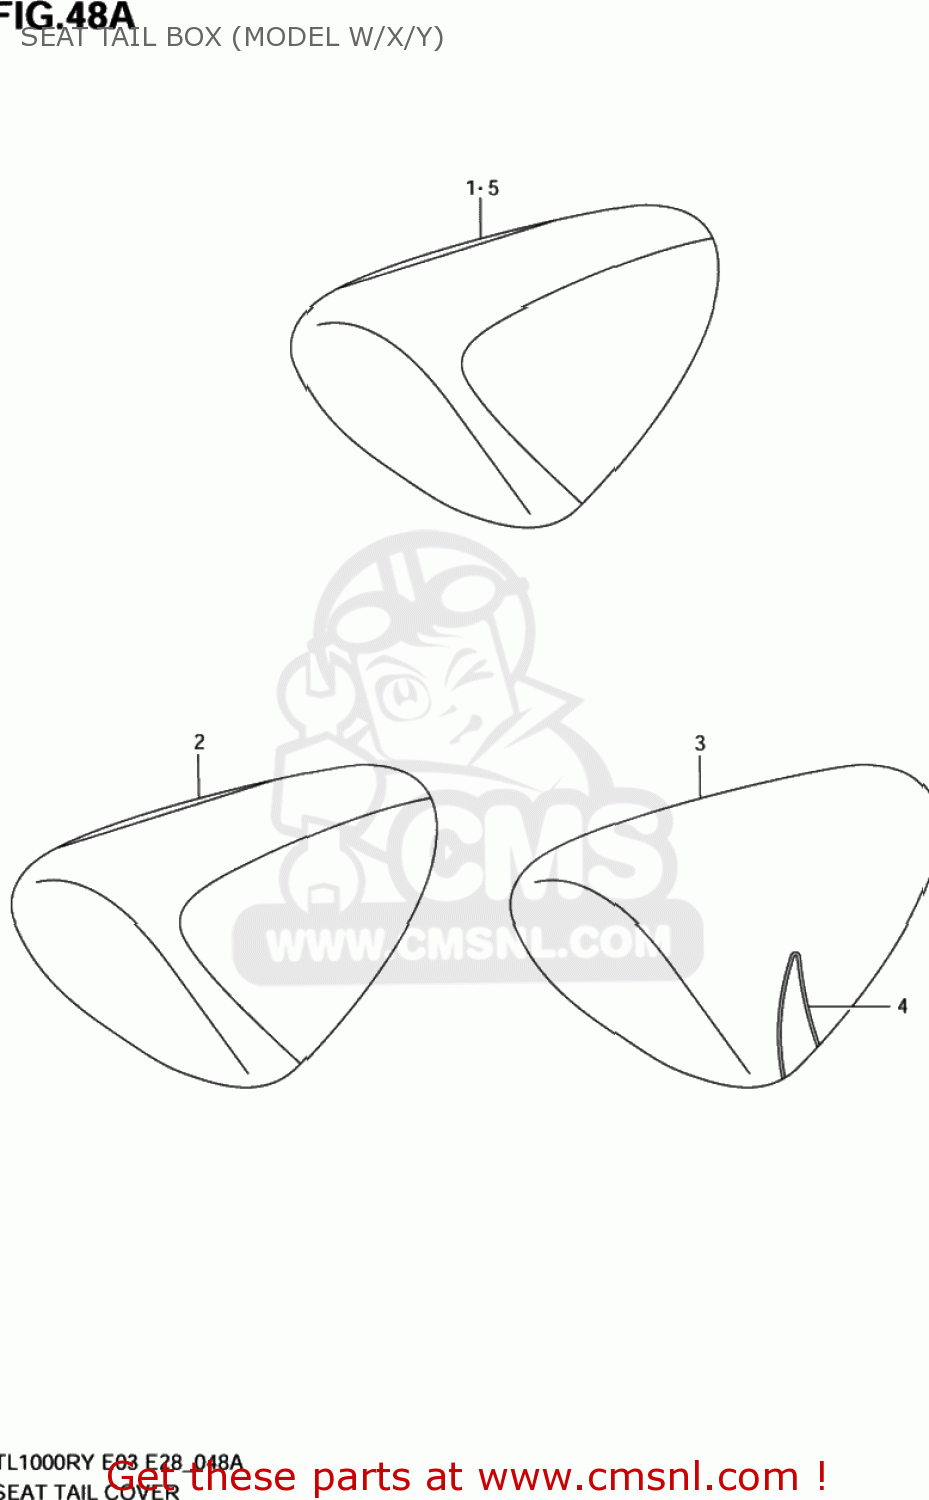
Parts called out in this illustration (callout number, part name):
1	BOX,SEAT TAIL
2	BOX,SEAT TAIL
3	BOX ASSY,SEAT TAIL(WHITE)
4	TAPE SET,SEAT TAIL BOX
5	BOX,SEAT TAIL
